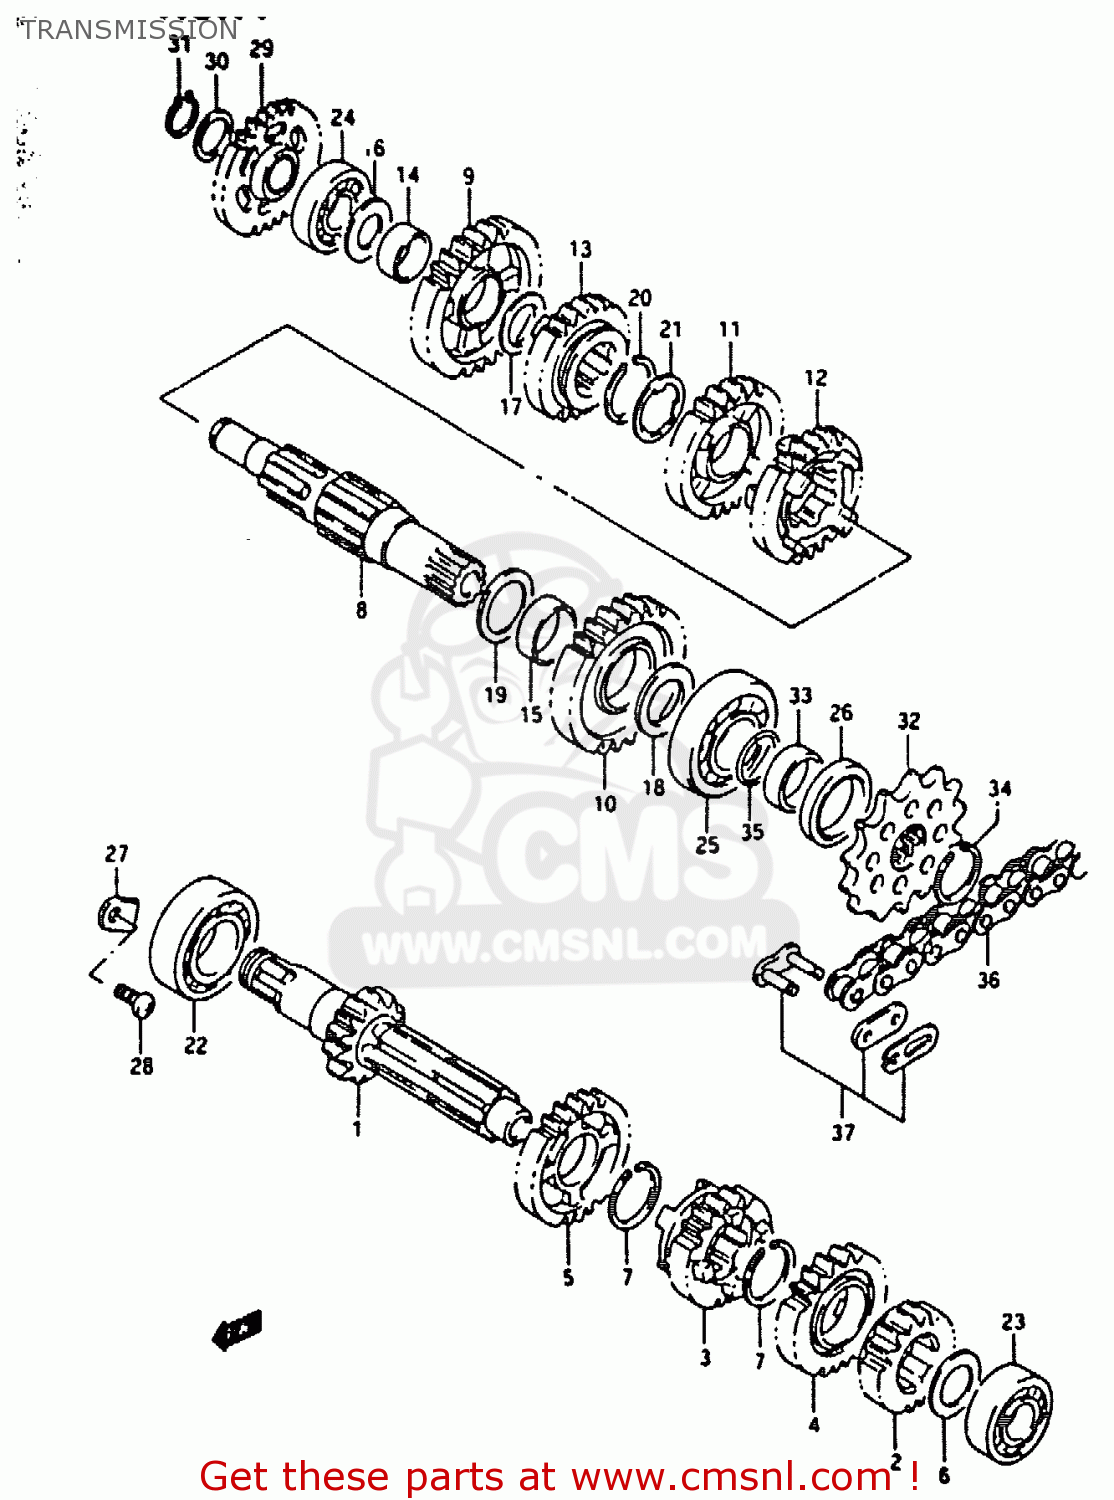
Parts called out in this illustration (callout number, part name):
1	SHAFT,COUNTER
2	GEAR,2ND DRIVE(NT:15)
3	GEAR,THIRD DRIVE (NT:16)
4	GEAR,FOURTH DRIVE (NT:22)
5	GEAR,5TH DRIVE(NT:22)
6	WASHER,THRUST
7	CIRCLIP
8	SHAFT,DRIVE
9	GEAR,1ST DRIVEN(NT:32)
10	GEAR,2ND DRIVEN(NT:26)
11	GEAR,3RD DRIVEN(NT:22)
12	GEAR,FOURTH DRIVEN (NT:24)
13	GEAR,FIFTH DRIVEN (NT:19)
14	BUSH(20X24X10)
15	BUSH(25X28X10)
16	WASHER
17	WASHER, 1ST DRIVEN GEAR NO.2
18	THRUST WASHER
19	WASHER
20	CIRCLIP
21	WASHER,LOCK
22	BEARING, RH
23	BEARING(17X40X12)
24	BEARING(17X40X12)
25	BEARING(22X56X15)
26	SEAL,OIL(28X38X6)
27	RETAINER
28	SCREW
29	GEAR,KICK STARTER IDLE(NT:27)
30	SHIM
31	CIRCLIP
32	SPROCKET,ENGINE
33	SPACER,ENGINE SPROCKET
34	CIRCLIP
35	O RING(D:1.9,ID:21.8)
36	CHAIN,DRIVE
37	JOINT,CHAIN
